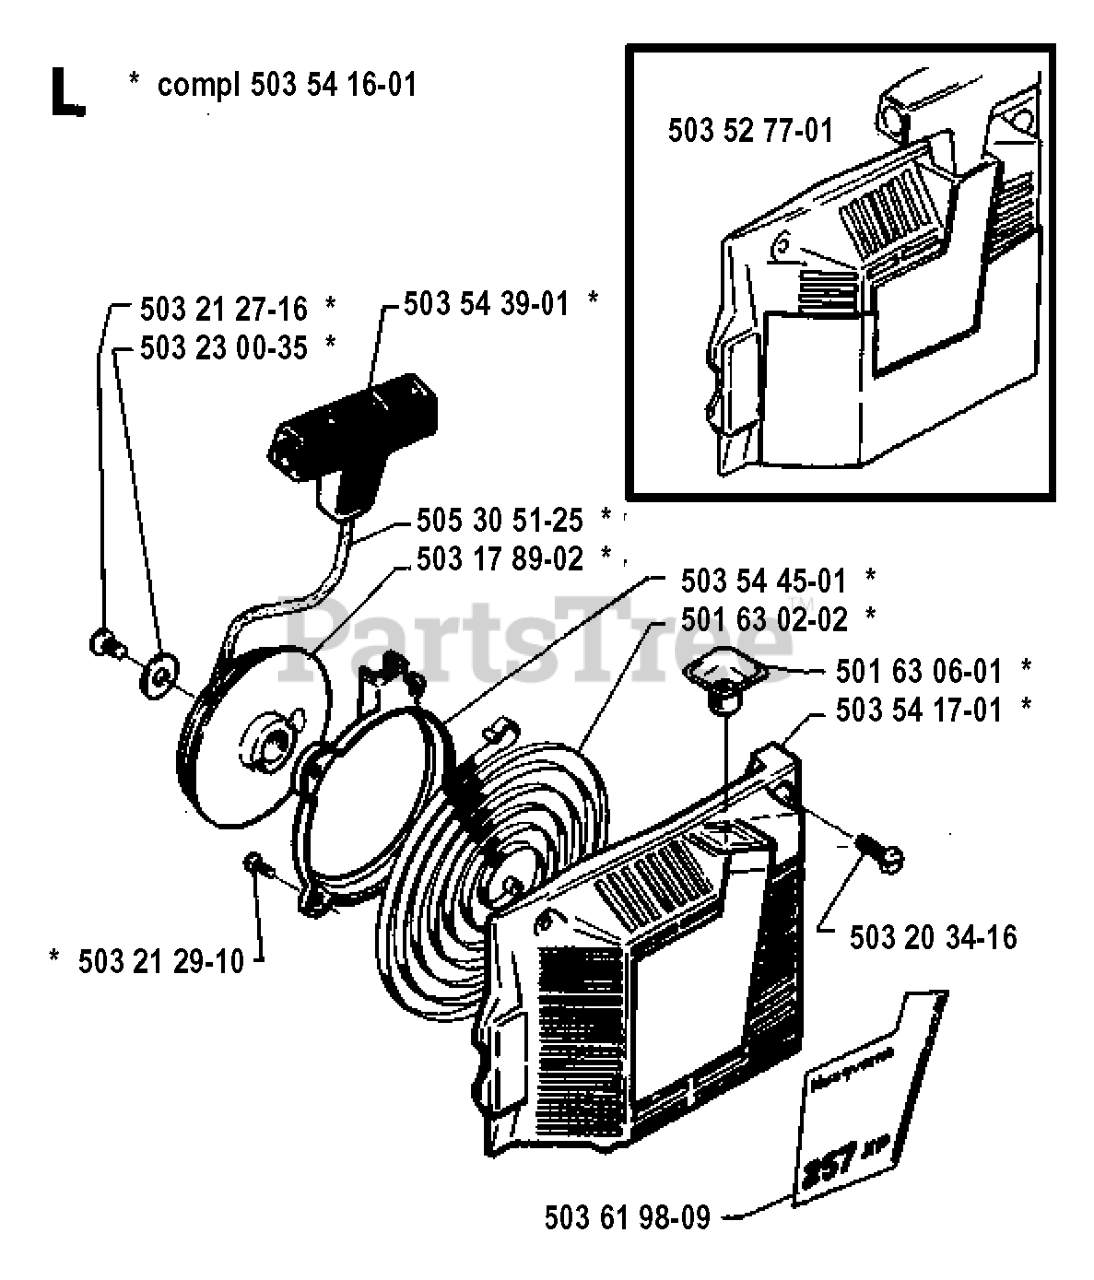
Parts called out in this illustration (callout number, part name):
1	RP WHEEL.STEER.HUSQ.PREM.OVMLD
2	AXLE.CAST.IRON
4	SPINDLE.WELDED.LH.15"TEX
5	SPINDLE.WELDED.RH.15"T
6	THRUST WASHER
9	CAP.SPINDLE.BLACK
14	WASHER, LOCK 3/8
15	NUT CROWNLOCK 3/8-24
16	SHAFT, STEERING
19	PLATE.STEER.DDL.NLT/NG
21	ADAPTER, WHEEL STNG..
22	STEERING.SUPT.LOWER.
26	RP INSERT.CAP.WHL.STRG.HUSQ.
28	SCREW, 3/8-16X3/4
35	GEAR.SECTOR.PLATE.DDL.
45	WASHER 9/16"ID, 2 3/8"OD
50	NUT LOCK FLG 3/8-16 UNC
51	NUT.HEX.1/2-20
53	WASHER.HARDENED
55	SPACER.BRACE.AXLE
57	BRKT.UPSTOP.GT/LT.TEX
58	BOLT.SHOULDER.SECTOR.P
59	WASHER.THURST.SECTOR.S
60	NUT FLANGE LOCK 5/8-11
61	DRAGLINK.LH.BALLSTUD.D
62	DRAGLINK.RH.BALLSTUD.D
63	SCREW
64	RETAINER.CLIP.SPRING.S
65	BRACE.AXLE.FRONT.NLT/N
66	BOLT HEX FGHD 7/16-14 X 3 SERR
67	BUSHING.PM.FRONT AXLE
68	NUT.LOCK.FLANGE.7/16
69	WASHER.1.5X.505X.118
70	BRKT.DECK.SUSPENSION.F
78	THRUST WASHER
